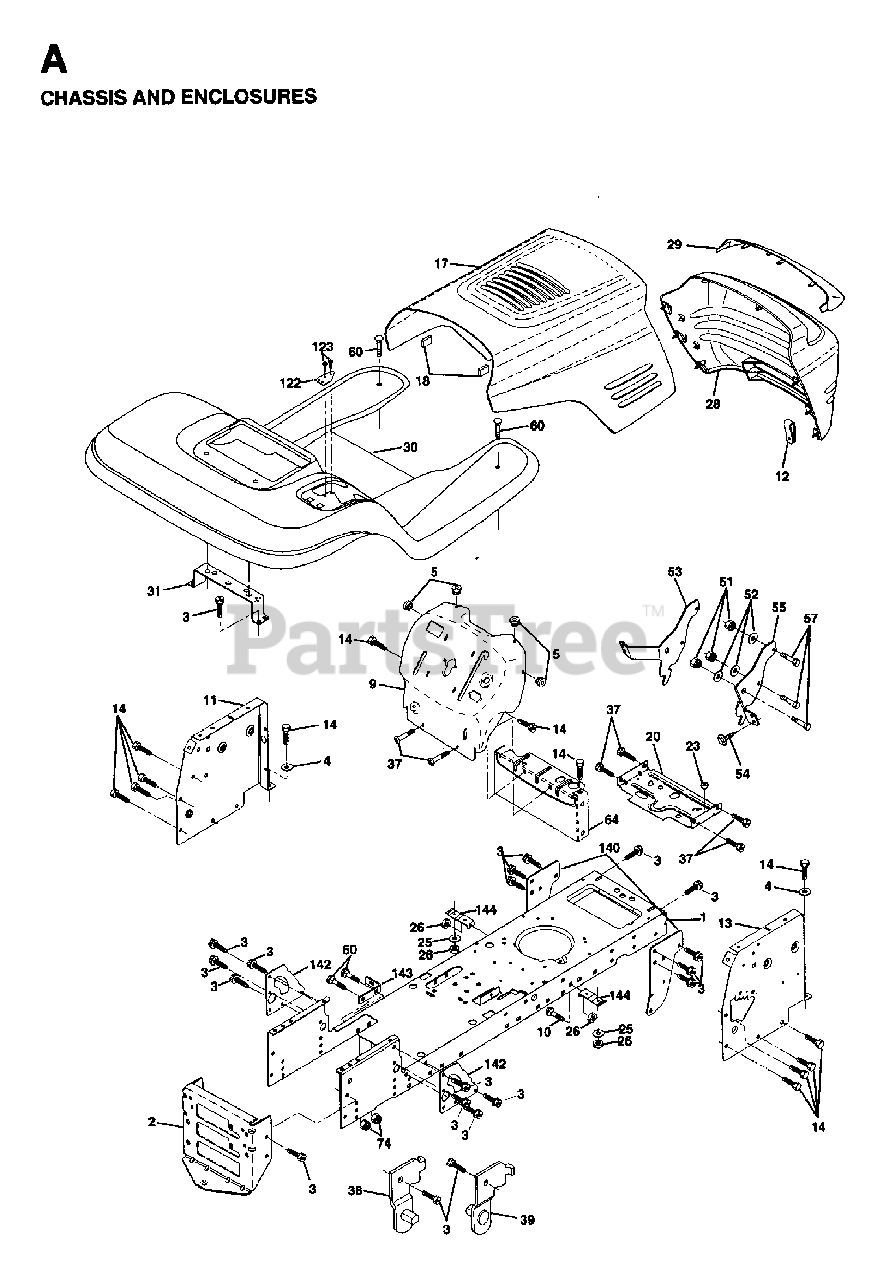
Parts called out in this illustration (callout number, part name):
1	CHASSIS WELDMENT
2	STRETCH DRAWBAR
3	SCREW
5	BUMPER.RUBBER.HOOD
10	BOLT D
11	PANEL DASH LH
13	PANEL DASH RH
18	BUMPER HOOD T
20	PLATE MTG
23	GROMMET T
25	WASHER
26	NUT
38	BRACKET LH PIVOT
39	BRACKET RH PIVOT
51	LOCKNUT
57	BOLT
64	DASH LOWER
74	LOCKNUT
122	BRACKET SHIFT STLT
140	BRACKET CHASSIS FRONT
142	PLATE REINFORCEMENT
143	BRACKET, SWAY BAR
144	BRACKET FOOTREST
